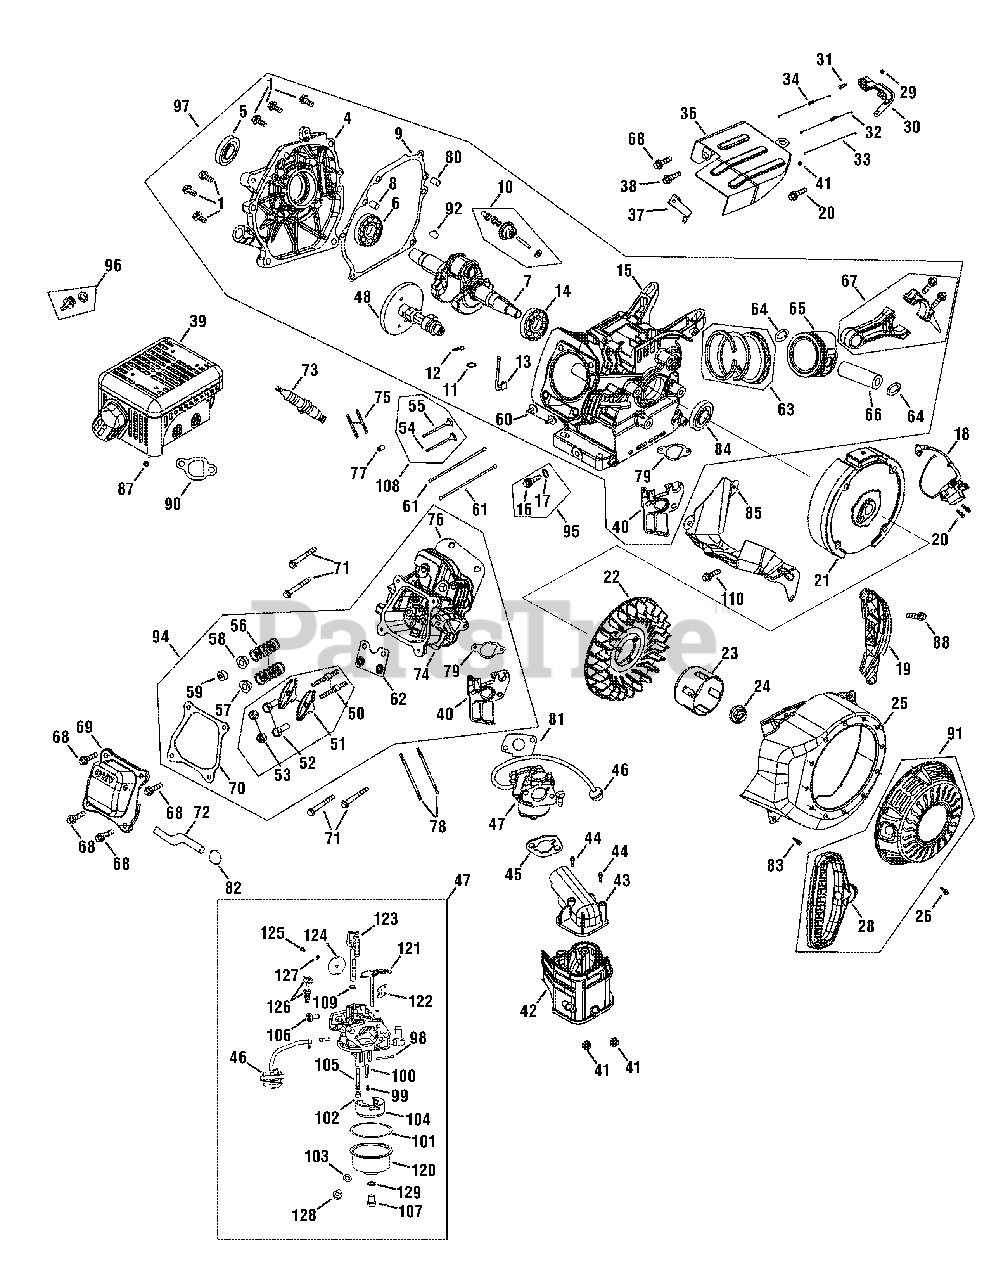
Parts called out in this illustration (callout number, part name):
1	Flange Bolt
2	O-Ring
4	Crankcase Cover
5	Oil Seal
6	Bearing
7	Crankshaft Assembly
8	Dowel Pin, 7 x 14
9	Crankcase Cover Gasket
10	Governor Assembly
11	O-Ring, 5.2 x 1.9
11	O-ring Gov. Shaft
12	Governor Arm Clip
13	Governor Arm Shaft
14	Bearing
15	Crankcase Complete
16	Oil Drain Plug Bolt
17	Oil Drain Plug Washer
18	Ignition Coil
19	Flywheel Baffle
20	Flange Bolt
22	Cooling Fan
23	Starter Cup
24	Nut
25	Blower Housing
26	Flange Bolt
28	Recoil Starter Handle
29	Nut
30	Governor Arm Bracket
32	Throttle Return Spring
33	Governor Rod
34	Governor Return Spring
36	Cover Shield
37	Governor Spring Bracket
38	Flange Bolt
39	Muffler Assembly
40	Carburetor Insulator Plate
41	Nut
42	Intake Heater Box Base
43	Intake Heater Box
45	Carburetor Gasket, Heater Box
45	Heat Pipe Intake Gasket
46	Primer
47	Carburetor Assembly
48	Camshaft Assembly
50	Pivot Bolt
51	Rocker Arm
52	Valve Adjusting Nut
53	Pivot Locking Nut
54	Intake Valve
55	Exhaust Valve
56	Valve Spring
57	Intake Valve Spring Seat
58	Exhaust Valve Spring Seat
59	Exhaust Valve Adjuster
60	Valve Lifter
61	Push Rod Kit
62	Push Rod Guide Plate
63	Piston Ring Set - Oil
64	Piston Pin Clip
65	Piston
66	Piston Pin
67	Connecting Rod Complete
69	Valve Cover
70	Head Cover Gasket
70	Valve Cover Gasket
72	Breather Hose
73	Spark Plug
74	Cylinder Head - Complete
75	Muffler Stud Assembly
76	Cylinder Head Gasket
77	Dowel Pin, 10 x 16
78	Carburetor Studs
79	Carburetor Insulator Gasket
80	Dowel Pin, 9 x 14
81	Carburetor Gasket
82	Hose Clamp
84	Oil Seal, 22 x 35 x 7
84	Oil Seal
85	Cylinder Baffle
88	Flange Bolt
90	Muffler Gasket
91	Recoil Starter Assembly
92	Flywheel Key
94	Cylinder Head Assembly
95	Oil Drain Plug and Washer Assembly
96	Dipstick Assembly
97	Short Block Assembly
98	Float Pin
99	Needle Valve Spring
100	Needle Valve
101	Bowl Gasket
102	Main Jet
103	Fuel Drain Plug Gasket
104	Float
105	Main Nozzle
106	Idle Speed Adjusting Screw
107	O-Ring- Main Cup Bolt
108	Valve Kit
109	Throttle Shaft Dust Seal
110	Bolt
120	Fuel Bowl
121	Choke Shaft
122	Choke Plate
123	Throttle Shaft
124	Throttle Plate
125	Screw
126	Idle Jet Assembly
127	Lock Washer
128	Drain Bolt
129	Fuel Bowl Gasket
